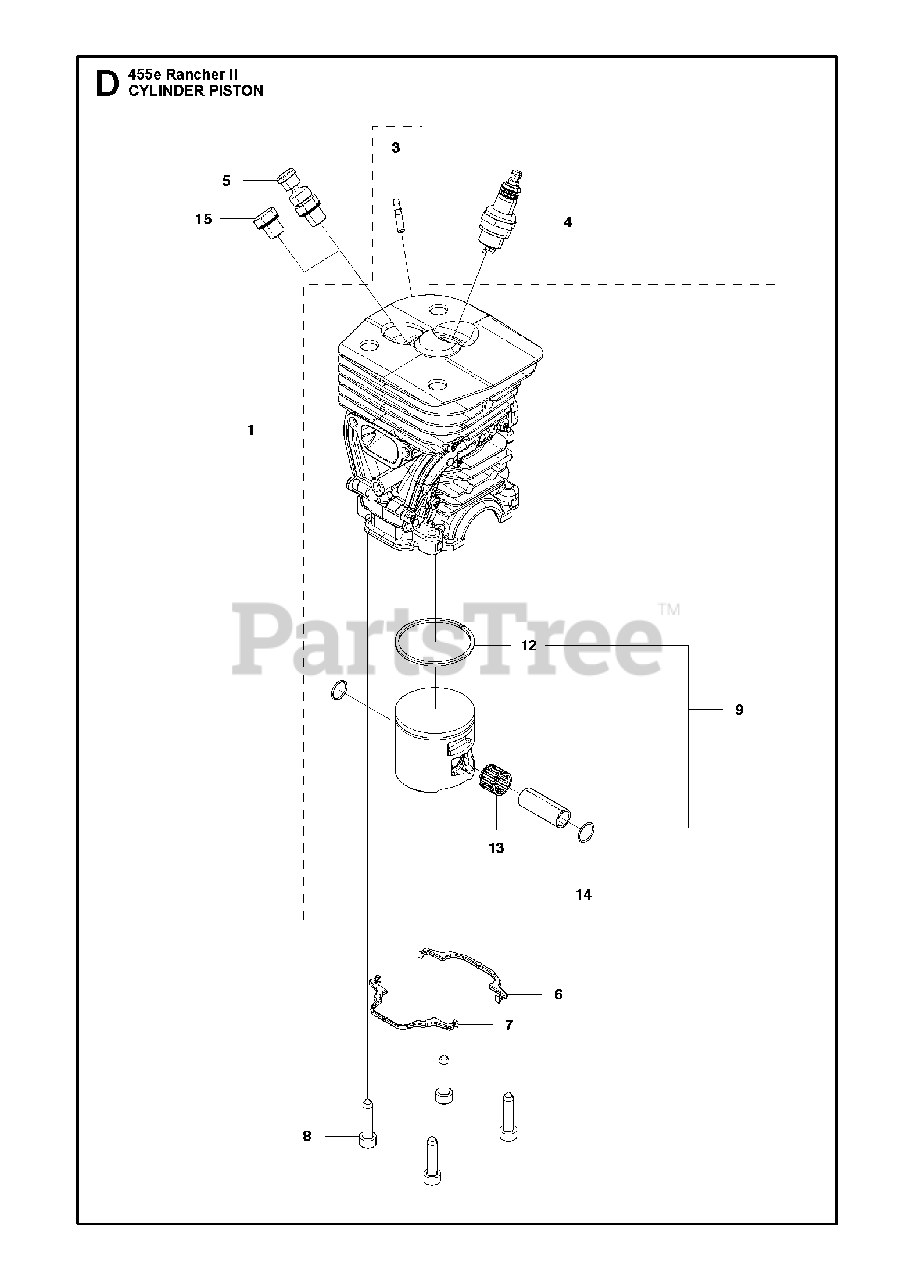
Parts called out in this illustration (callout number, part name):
1	CYLINDER ASSY
3	FITTING
4	BPMR7A NGK SPARK PLUG
5	RP VALVE
9	PISTON ASSY
12	PISTON RING
13	NEEDLE BEARING
14	CLIP
15	CYLINDER PLUG
